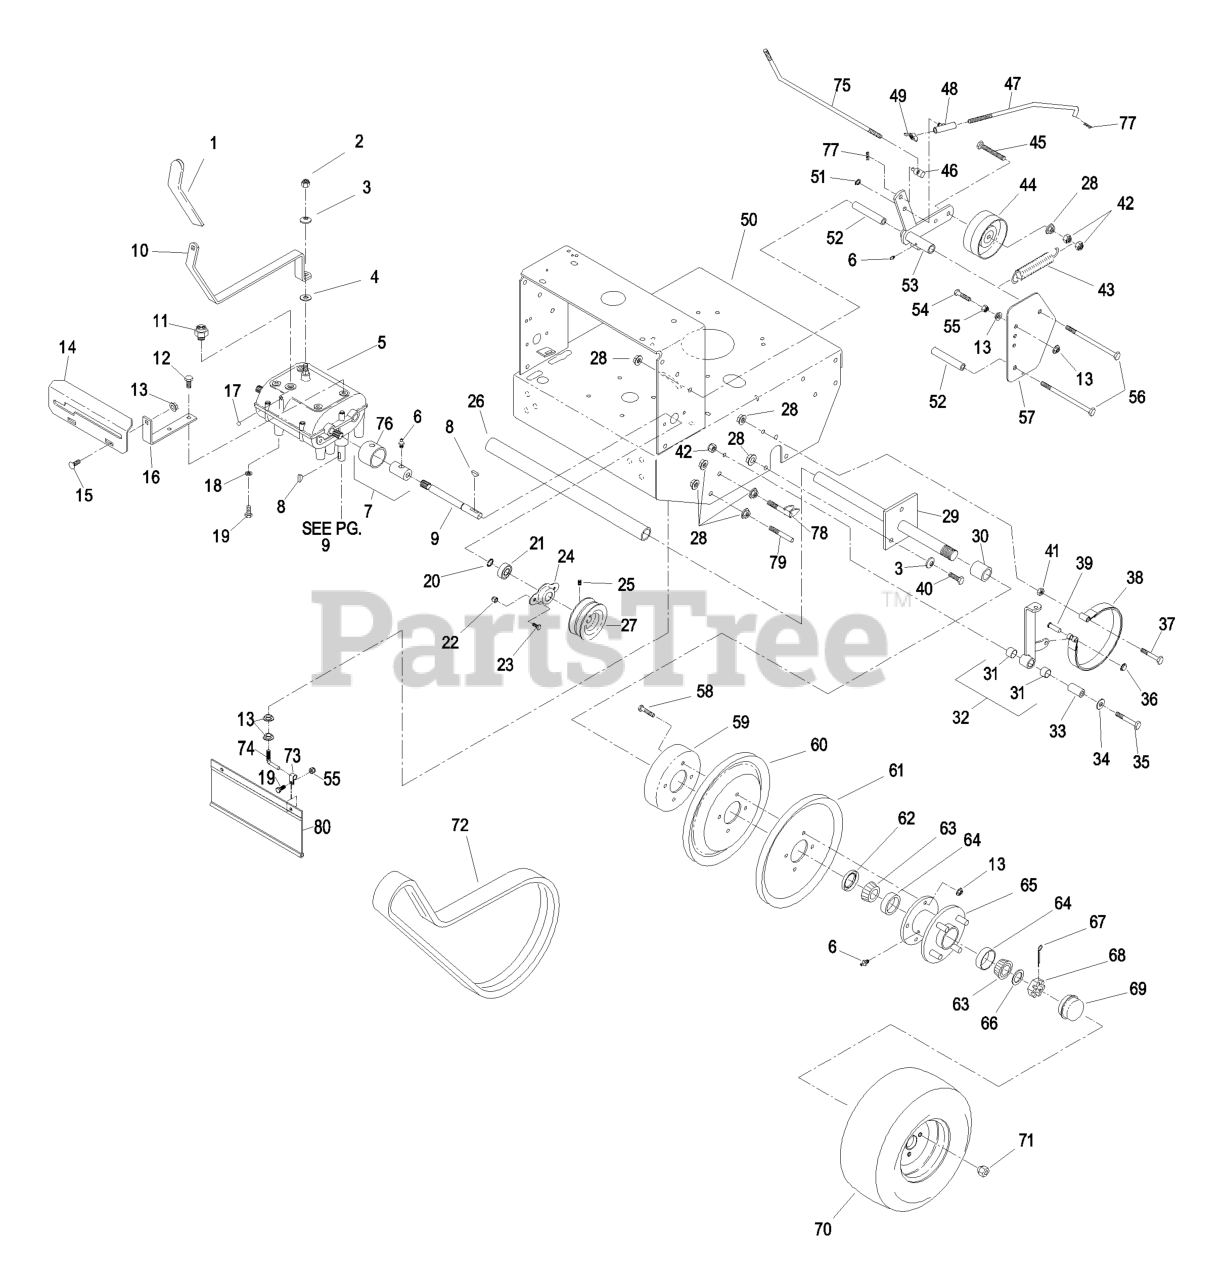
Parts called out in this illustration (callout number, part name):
1	GRIP,FOAM
2	NUT-LOCK
3	WASHER-BELLEVILLE
6	FITTING-GREASE
7	ASM,COUPLER/ZERK
8	KEY-WOODRUFF
9	SHAFT-TRANSMISSION
10	ASM,SHIFT LEVER
11	SWITCH-START, NEUTRAL
12	SCREW-HWH, THREAD CUT
14	PLATE,SHIFTER W/DECAL
15	BOLT-CARR
16	BRACKET-PLATE, SHIFT
17	BALL,DETENT (SERVICE ONL
18	WASHER-LOCK
19	SCREW-HH
20	RING-RETAINING
21	BEARING-SHAFT
22	NUT-LOCK, NI
23	SCREW-HH
24	FLANGE-OUTPUT
25	SCREW-SET
26	SLEEVE,AXLE
27	Sheave, Transmission Output
28	NUT-HHF, WHIZ
30	SPACER,WHEEL SHORT
31	SLEEVE-BUSHING
32	ASM,RH BRAKE LEVER W/BSHG
33	BUSHING-PIVOT
34	WASHER-FLAT
35	SCREW-HH
36	RING-RETAIN,PUSH,EXT,FLAT
37	SCREW-HH
38	BAND-BRAKE
39	PIN-CLEVIS
40	SCREW-HH
41	NUT-JAM
42	NUT-LOCK, NI
43	SPRING-EXTENSION
44	IDLER-WHEEL, DRIVE
45	SCREW-HH
46	SWIVEL-DRIVE LEVER, 3/8 L
49	WINGNUT-NYLOCK
50	DECK,ENGINE W/DECALS
51	RING-RETAINING
52	SPACER-SHIELD
53	WLD,RH IDLER ARM
54	SCREW-HH
55	NUT-LOCK, NI
56	SCREW-HH
57	SHIELD,WHEEL DRIVE
58	SCREW-HH
59	DRUM-BRAKE
60	SHEAVE,WHEEL DRIVE
61	SHEAVE,WHEEL DRIVE
62	SEAL-GREASE
63	Cone-Bearing Tapered Roller
64	CUP-BEARING
65	HUB/WHEEL ASM
66	WASHER-SPACER
67	PIN-COTTER
68	NUT-SHH
69	CAP-GREASE
70	WHEEL AND TIRE ASM
71	NUT-LUG
72	BELT,WHEEL DRIVE BANDED
73	CLIP-LOOM
74	MOUNT,DRAG SHIELD
75	LINKAGE,DRIVE (PLT)
76	GUARD-COUPLER
77	PIN-COTTER
78	SCRAPER
80	SHIELD-TRAILING
